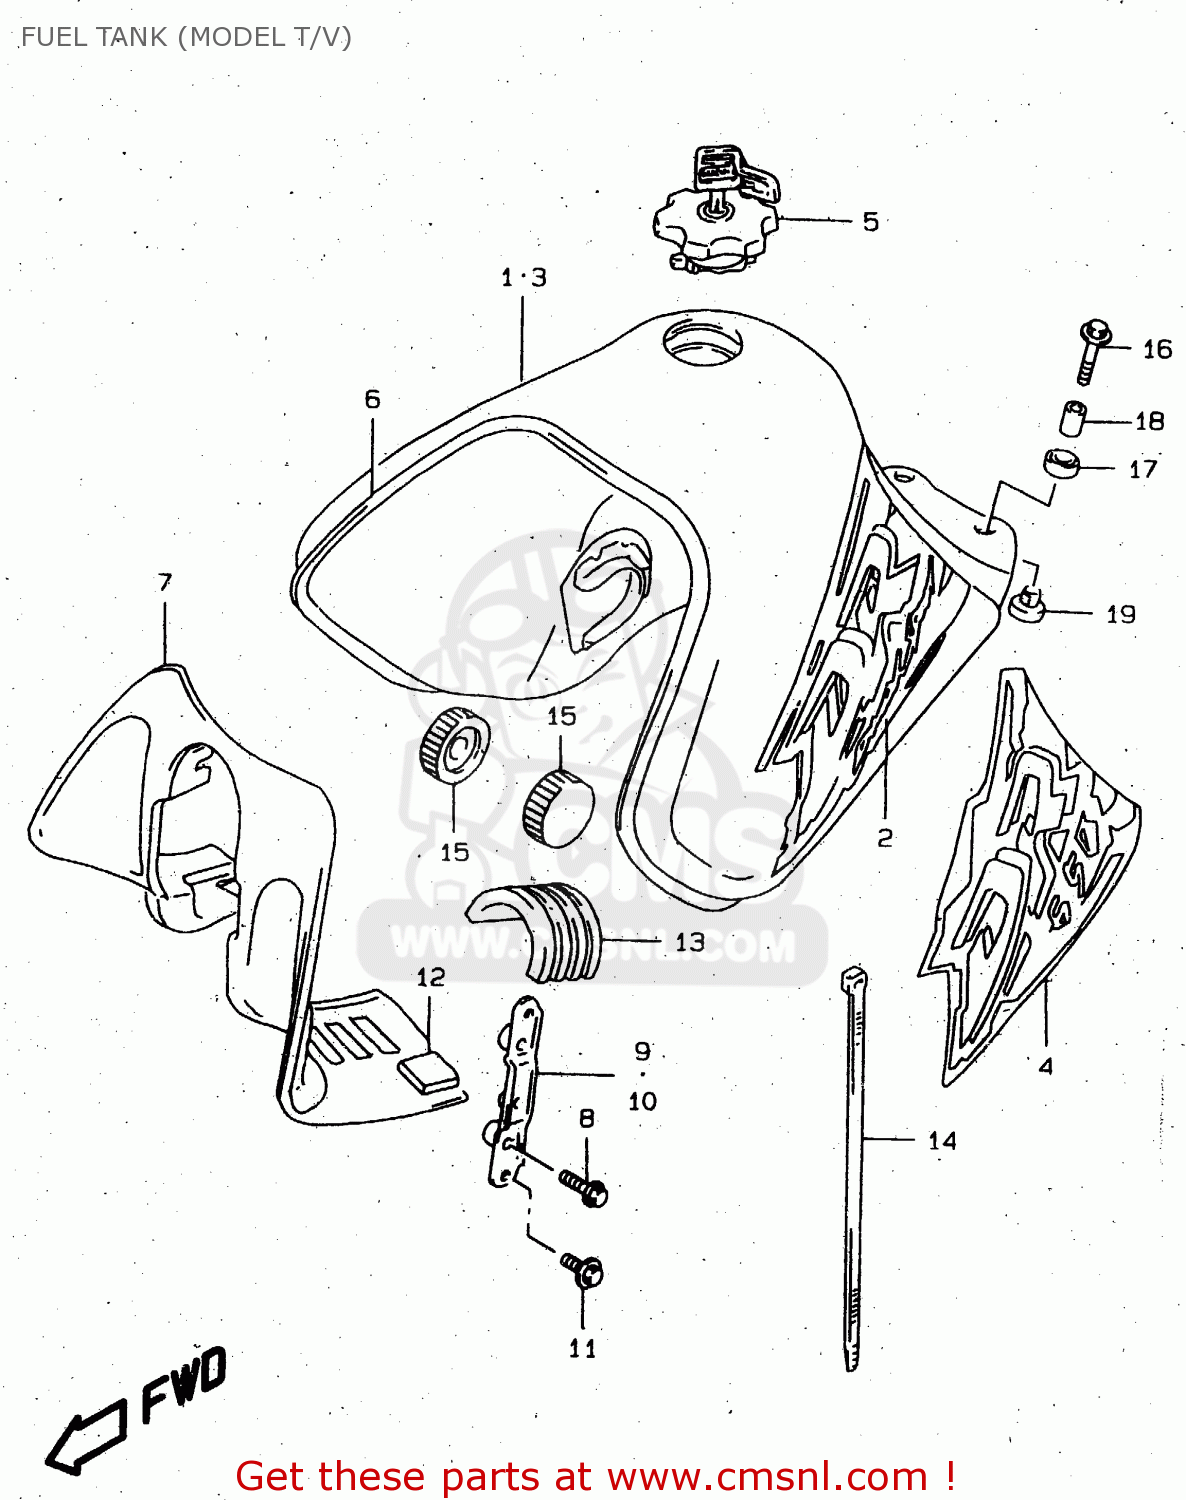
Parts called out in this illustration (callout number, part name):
1	TANK ASSEMBLY,FUEL
2	TAPE SET,FUEL TANK
3	TANK ASSEMBLY,FUEL
4	TAPE SET,FUEL TANK
5	CAP SET,FUEL TANK
6	MOLDING,FUEL TANK
7	COVER,FUEL TANK FR
8	BOLT 6X14
9	BRACKET,FUEL TANK COVER,R
10	BRACKET,FUEL TANK COVER,L
11	BOLT
12	CUSHION,HEADLAMP COVER
13	CUSHION,FUEL TANK UPR
14	CLAMP(L:250)
15	CUSHION,FUEL TANK FR
16	BOLT(6X30)
17	CUSHION
18	SPACER
19	CUSHION
